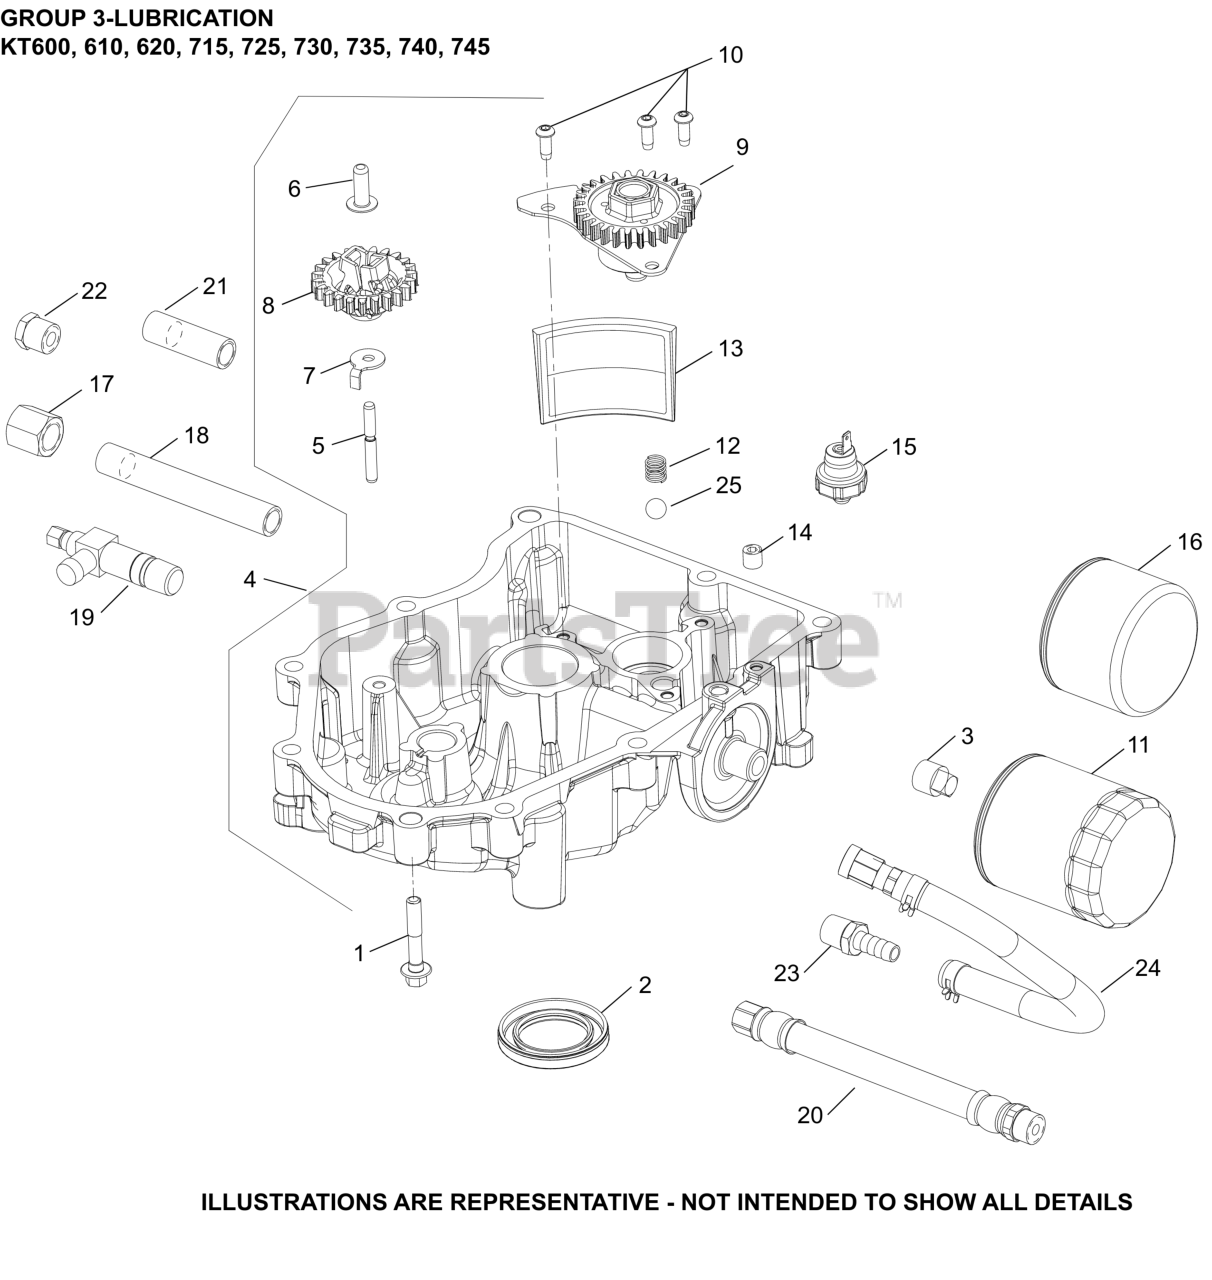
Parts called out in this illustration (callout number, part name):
1	SCREW, FLG M8X1.25X45
3	PLUG, SQ HD PIPE 3/8"
4	OIL PAN ASSEMBLY, (ROLLER BURNISHED)
6	PIN, GOVERNOR REGULATING
7	TAB, LOCKING
8	KIT, GOVERNOR GEAR
10	SCREW, BUTTON HEAD
11	OIL FILTER
12	SPRING, COMPRESSION
13	SCREEN, OIL
15	SENSOR, OIL PSI
25	PRESSURE RELIEF BALL
NI	SHAFT, GOVERNOR GEAR
